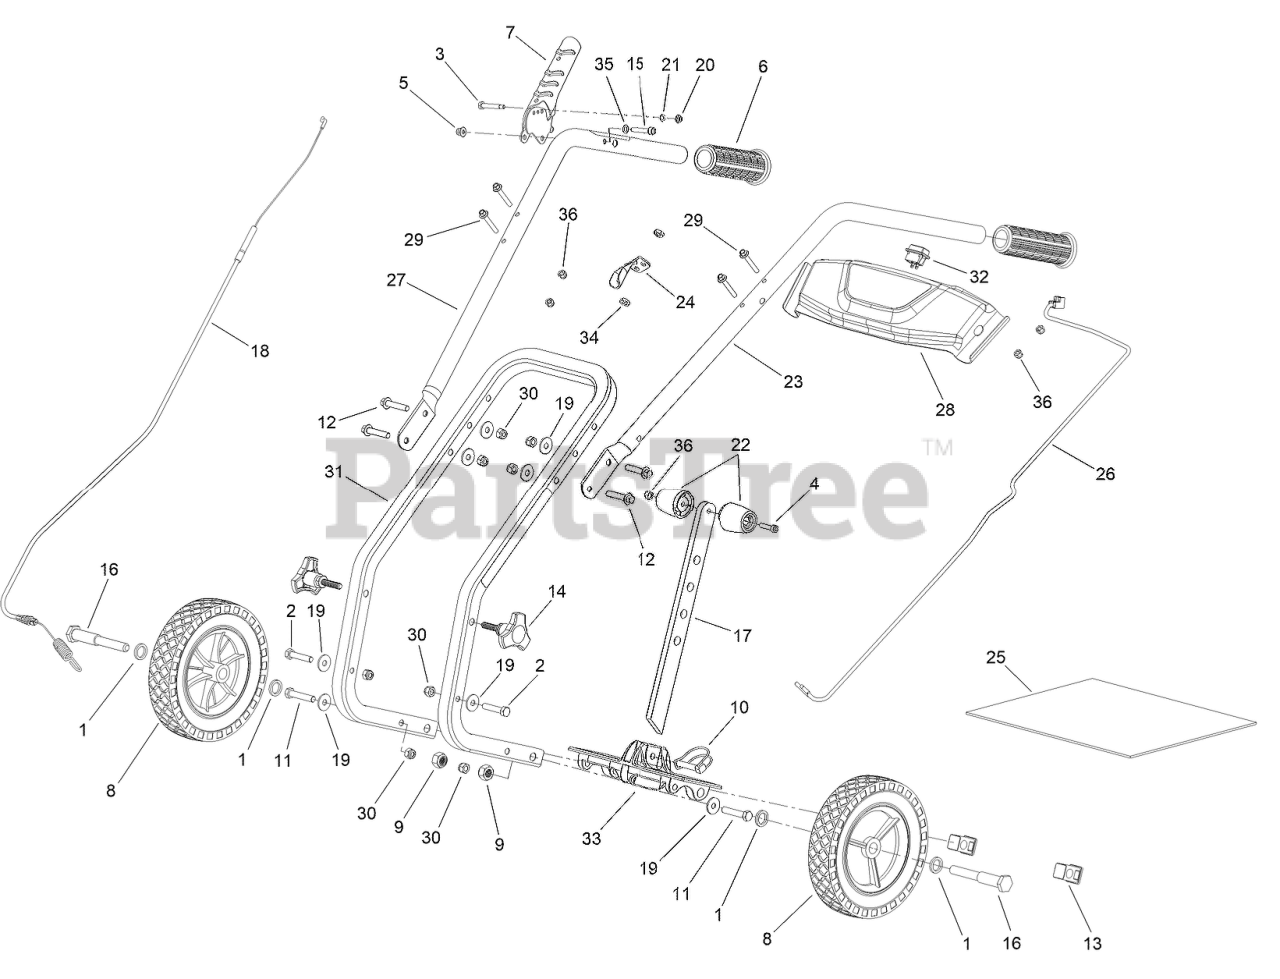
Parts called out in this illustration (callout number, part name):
1	WASHER-FLAT
2	SCREW-HH
3	SCREW-HH
4	SCREW-SHCS
5	NUT-HEX
7	LEVER-CLUTCH
9	NUT-HEX
10	PIN-CLEVIS, LOCKING
11	SCREW-HH
12	SCREW-RHF
13	PLUG-SQUARE
15	SCREW-SHCS
16	SCREW-SHOULDER
17	DRAG STAKE
19	WASHER-FLAT
20	NUT-HEX
21	WASHER-FLAT
22	HANDLE
23	HANDLEBAR-LEFT
24	BRACKET-CABLE
25	BAG-MANUAL
26	HARNESS-WIRING
27	HANDLEBAR-RIGHT
28	DASH-TILLER
29	SCREW-HHF
30	NUT-HEX
32	SWITCH
33	HOLDER-DRAG STAKE
35	WASHER
36	NUT-HEX
